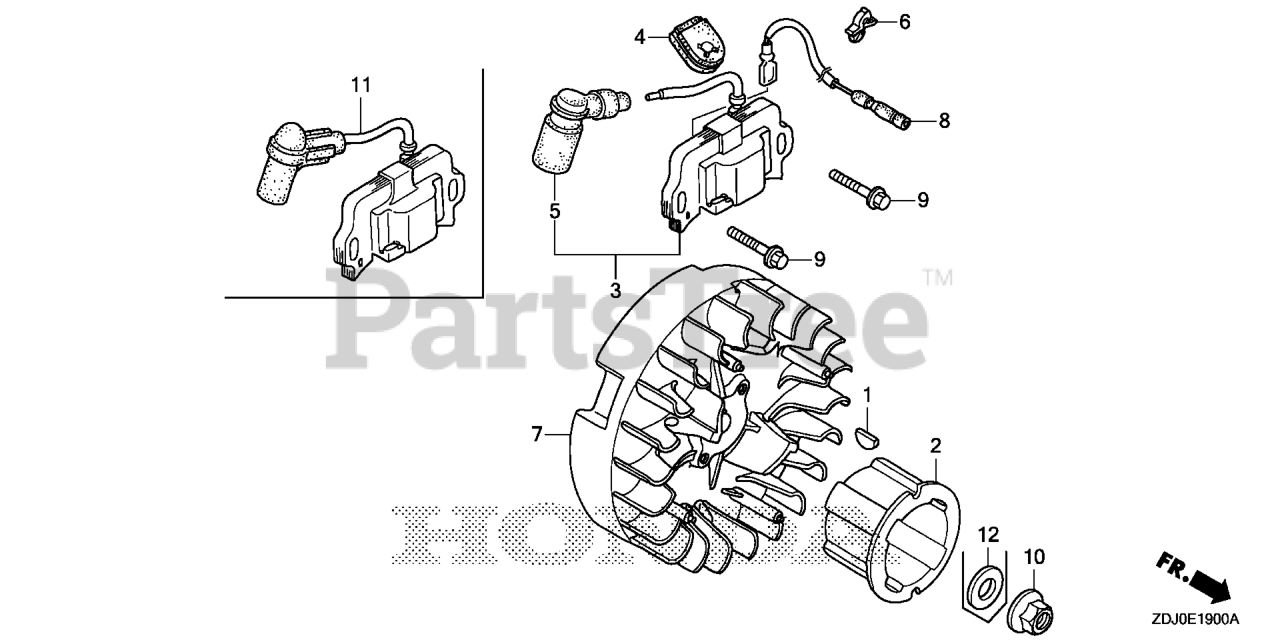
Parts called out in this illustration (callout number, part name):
1	KEY, SPECIAL WOODRUFF (25X18)
2	PULLEY, STARTER
4	GROMMET, WIRE
6	CLIP, IGNITION WIRE (8MM)
8	WIRE, STOP SWITCH
9	BOLT, FLANGE (6X20) (CT200)
10	NUT, SPECIAL (14MM)
11	COIL ASSY., IGNITION
